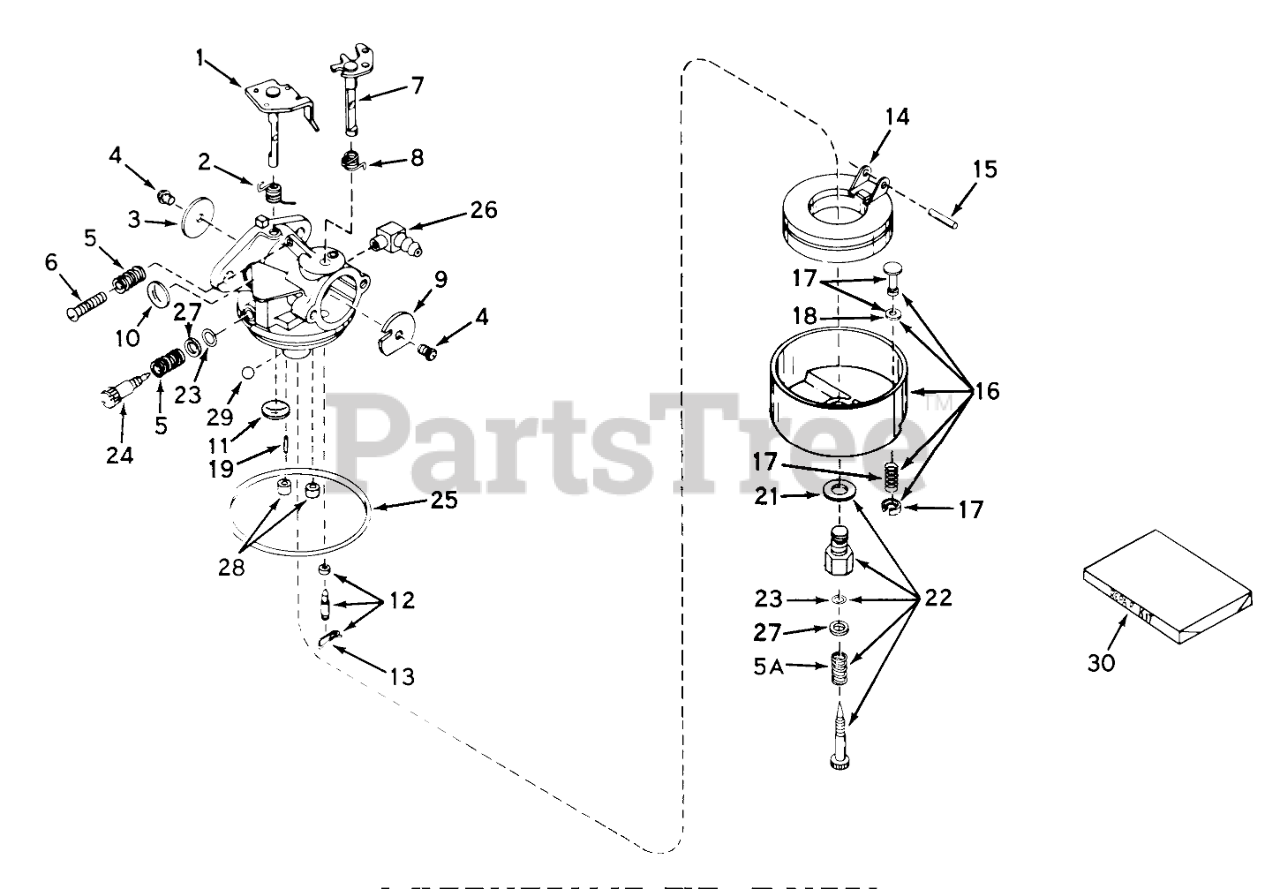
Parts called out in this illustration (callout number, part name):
1	Shaft & Lever Assy.
2	Spring, Throtte Return
3	Shutter-Throttle
4	Screw-Shutter
5	Spring-Tension
6	Screw-Throttle Crack Screw / Idle Speed
7	Shaft& Lever Assy., Choke
8	Spring, Choke return
9	Shutter, Choke
10	Plug-Welch, Idle Mixture Well
11	Plug-Welch, Atmospheric Vent
12	Inlet Needle, Seat & Clip Assy. (Incl. No. 13)
13	Clip-Spring
14	Float,Carburetor
15	Shaft-Float
16	Bowl & Drain Assy., Float (Incl. No. 17)
17	Plunger Assy., Drain (Incl. No. 18)
18	Gasket-Plunger, Drain
21	Washer-Bowl Nut
22	Adjustment Screw Assy., Main (Incl. Nos. 5A & 27)
23	"O"Ring
24	Screw, Idle Adj.
25	O Ring-Bowl, Float
26	Fitting Fuel Inlet
28	Plug, Cup
29	BalI, Steel
30	Repair Kit
